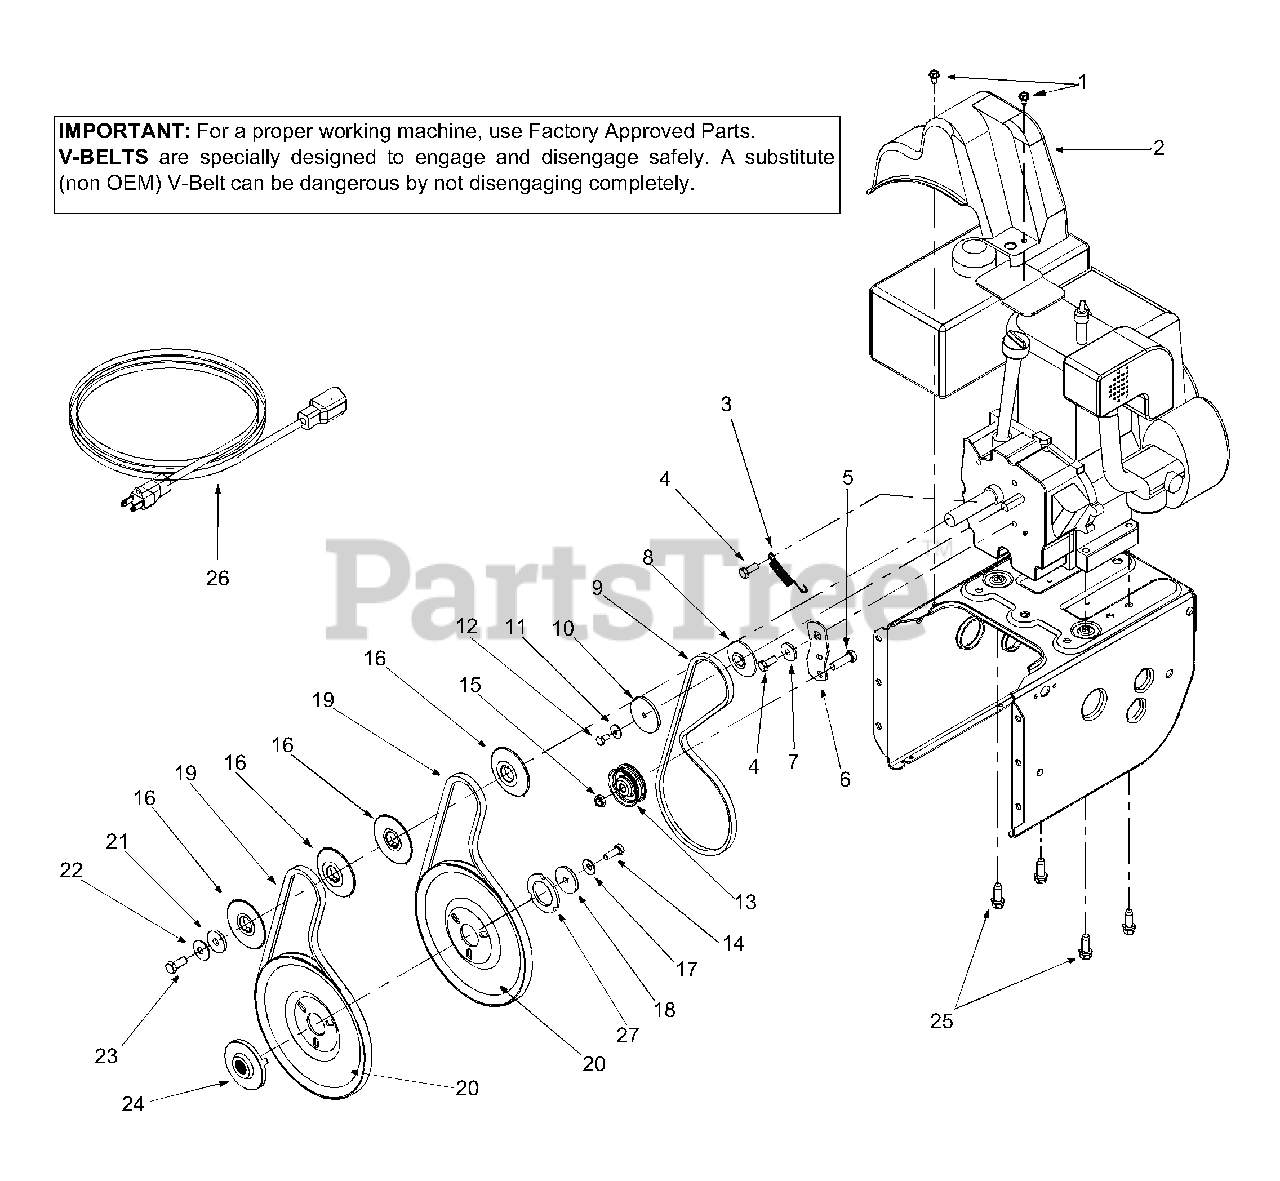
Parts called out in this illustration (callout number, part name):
1	Hex Washer Screw 1/4-20 x.625
2	Belt Cover
3	Extension Spring
4	Hex Screw 5/16-24 x.75
5	Hex Cap Screw 3/8-16 x 1.25
8	Pulley Half
9	V-Belt
10	Pulley Half
11	Bell Washer
12	Hex Cap Screw 1/4-28 x.50
13	Flat Idler
14	Lock Hex Cap Screw 5/16-24
15	Lock Jam Nut 3/8-16
16	Pulley Half
17	Bell Washer
18	Flat Washer
19	Belt
20	Auger Pulley
21	Flat Washer 3/8 x 1.25 OD
22	Bell Washer
23	Hex Cap Screw 3/8-24
24	Pulley Adapter
25	Hex Screw 3/8-16 x 1.0
26	Extension Cord, Three-Prong
27	Special Washer
